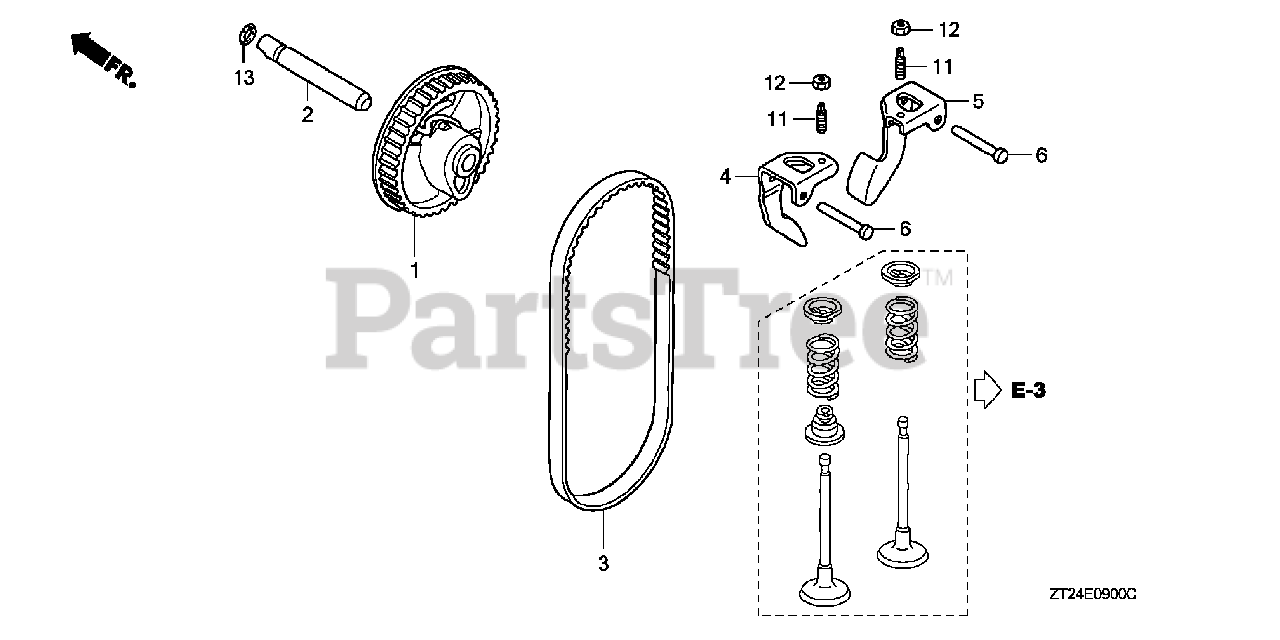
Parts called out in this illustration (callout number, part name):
1	PULLEY, CAMSHAFT
2	SHAFT, CAM PULLEY
3	BELT, TIMING (84HU7 G-200)
4	ARM, IN. VALVE ROCKER
5	ARM, EX. VALVE ROCKER
6	SHAFT, ROCKER ARM
11	SCREW, TAPPET ADJUSTING
12	NUT, TAPPET ADJUSTING
13	O-RING (6.8X1.9) (ARAI)
